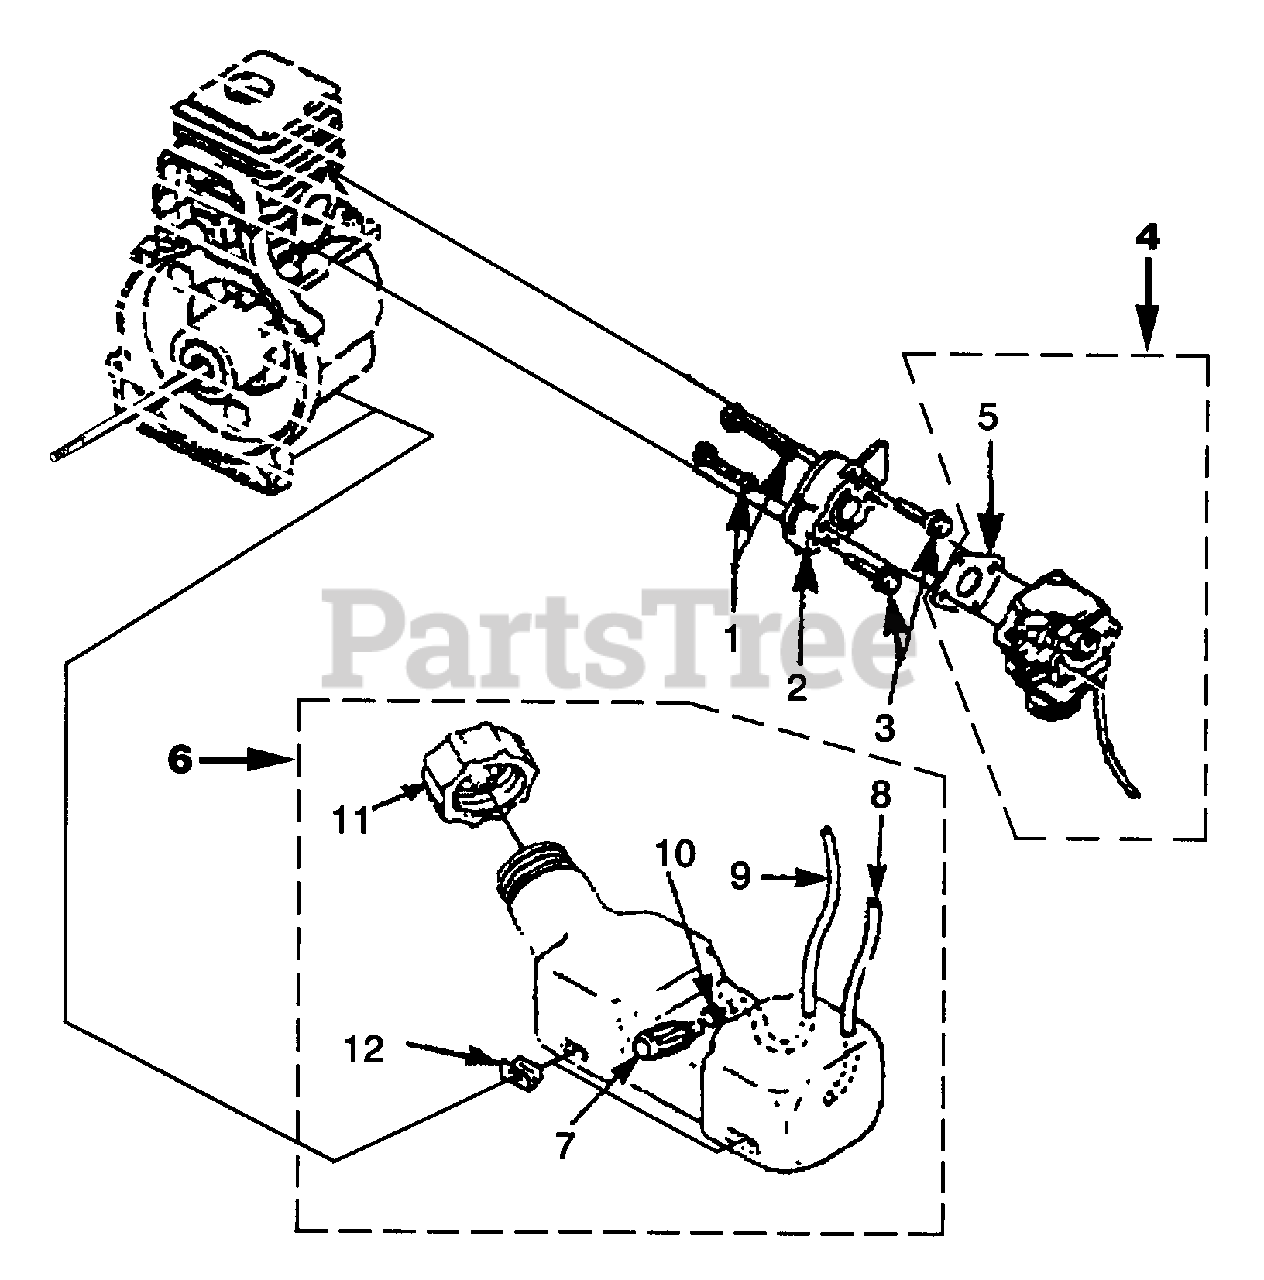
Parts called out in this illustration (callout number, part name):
1	SCREW - Machine (10-24 X 2-1/4")
2	HEAT DAM
3	SCREW - Taptite (10-24 X 1")
4	CARBURETOR KIT
5	GASKET - Carburetor
6	FUEL TANK
7	FILTER - Fuel
8	TUBING - Rubber (8")
9	TUBING - Rubber (8")
10	CLAMP - Wire
11	FUEL CAP
12	BUMPER - Rubber
